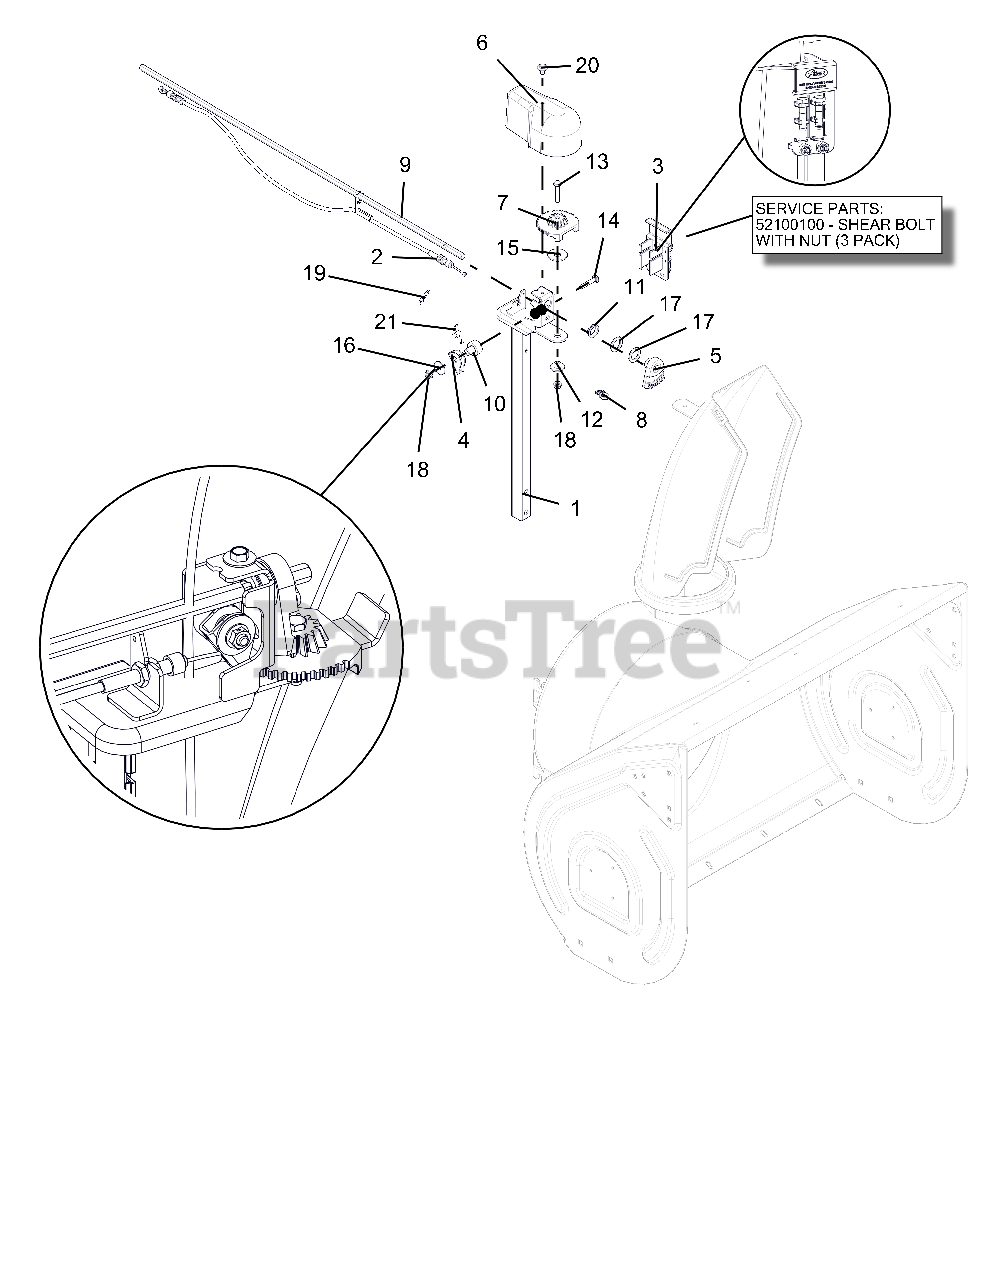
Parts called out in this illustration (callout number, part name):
1	PEDESTAL, CHUTE - QUICK STICK
2	CABLE, CHUTE LOCK, PRO
3	HOLDER W LARGE SHEAR BOLT /NUT
3	SHEAR BOLT SERVICE ASSEMBLY
4	ARM, LOCKING
5	GEAR, CHUTE-ACTUATION
6	COVER, CHUTE GEAR
7	GEAR, CHUTE
8	CLIP, CABLE GUIDE
9	ROD, HEX - CHUTE ROTATION
10	BUSHING, LOCK ARM
11	BUSHING, POLYLINER-.75 SNAPIN
12	BSHG-FLG .265X.477X.375X1.00
13	@BLT-HEX .25-20X1.50 GR5 YWZC
14	@BLT-RDHDSQNK .25-20X1.50 G5YZ
15	WSHR-FLT-NYL .515X1.375X.093
16	WSHR-FL-STL .281X1.000X.063
17	WSHR-FL-STL.754X1.125X.062YWZC
18	@NUT-LK-CTR-FLG .25-20 YWZC
19	PIN-HAIR INT .08X.18X1.18 YWZC
20	SCR-TAP .25-20X.50 LGHWH TR YZ
21	SG-TORS
